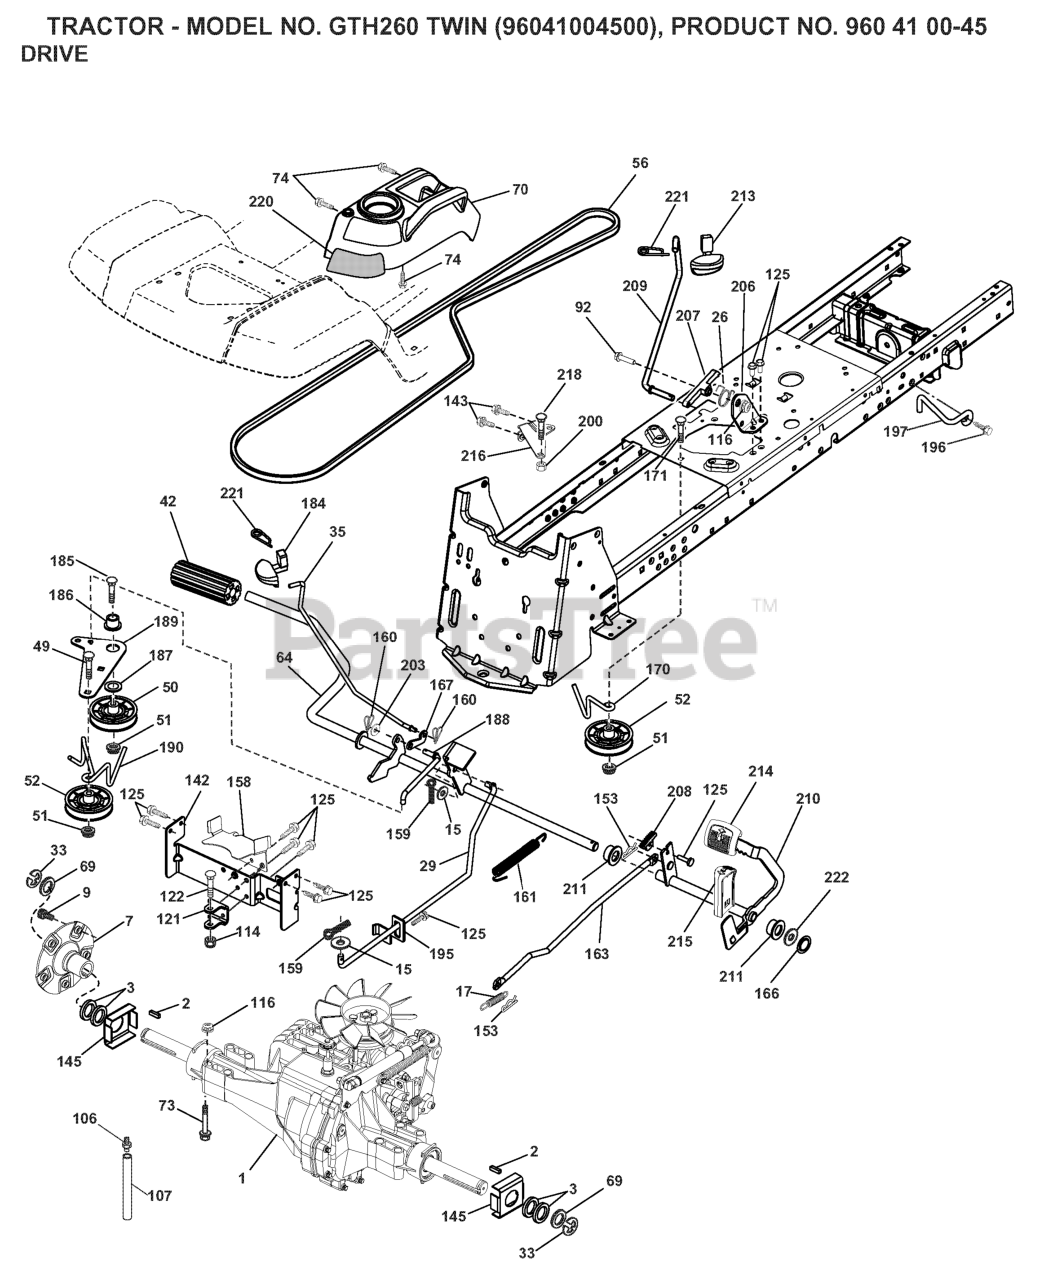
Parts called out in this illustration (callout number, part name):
2	KEY 1/4 X 2.5
7	HUB.ASM.WHEEL.REAR.23"TEX
15	WASHER
17	SPRING.BRAKE.HG3000/3500
26	SPRING.RETURN.CRUISE
29	ROD.BRAKE.HG3000/3500
33	E RING HYT
35	ROD.BRAKE.PARKING.GT.H
42	COVER, PEDAL (1 2)
50	IDLER.FLAT.910.OFFSET
51	NUT LOCK FLG 3/8-16 UNC
52	IDLER.V-GROOVE.910.OFFSET
56	BELT.V.GROUND.DRIVE
64	SHAFT.ASM.PEDAL.BRK.CNTR
70	RP CONSOLE.ASM.PCH.W/TB
73	BOLT HEX FLGHD 5/16-18X3 GR. 5
74	SCREW.HI-LO.CONSOLE
92	BOLT
106	CAP, VENT ASSY
114	NUT.71038.31-18.HEX.NYLOCK
116	NUT LOCK HEX FLANGE 5/16-18
121	BRACKET STRAP TORQUE
122	BOLT.5/16-18X2.5
125	SCREW
142	STRAP.TORQUE.HG3000/K46
143	Screw 5/16-18 x 1/2 Hex, Self Tapping 5/16-18 x 1/2
145	WASHER.AXLE.FLANGE.HG-3000
153	RETAINER M
158	KEEPER BELT
159	COTTER PIN
160	RETAINER CLIP
161	SPRING.RETURN.CLUTCH.2006
166	NUT.PUSH.625.2006
167	LATCH.BRAKE.SPRING
170	KEEPER.V-IDLER.CENTER.
184	HANDLE.PARKG.BRK.HUSQ X667
186	SPACER.RETAINER
187	WASHER 12/32X2X10GA
188	RP.LINK.CLUTCH.GROUND.DRIVE
189	BELLCRANK.GROUND.DRIVE.TEX.
190	KEEPER.BELLCRANK.DRIVE
195	RETAINER.ROD.BRAKE.HG3000.TEX
196	SCREW 3/8-16X1
197	BRKT.ANIT-ROTATION.CLUTCH
200	NUT.CENTERLOCK.5/16-
203	WASHER
206	BRKT.MOUNT.LATCH.CRUIS
207	LATCH.CONTROL.CRUISE
208	GEAR.SECTOR.CONTROL.CR
209	ROD.CONTROL.CRUISE.GT.
210	ROCKER.ASM.PEDAL.CONTR
211	BEARING.NYLON
213	KNOB.CONTROL.CRUSIE.HU
214	PEDAL.FORWARD.TEX.GT.4
215	PEDAL.REVERSE.TEX.GT.4
216	BRACKET.PULLEY.IDLER.W/TEX
218	BOLT.5/16-18X1-1/4 FULL.THREAD
220	REFLECTOR.RH.TEX GT
221	RETAINER.SPRING.CLIP.H
222	WASHER
